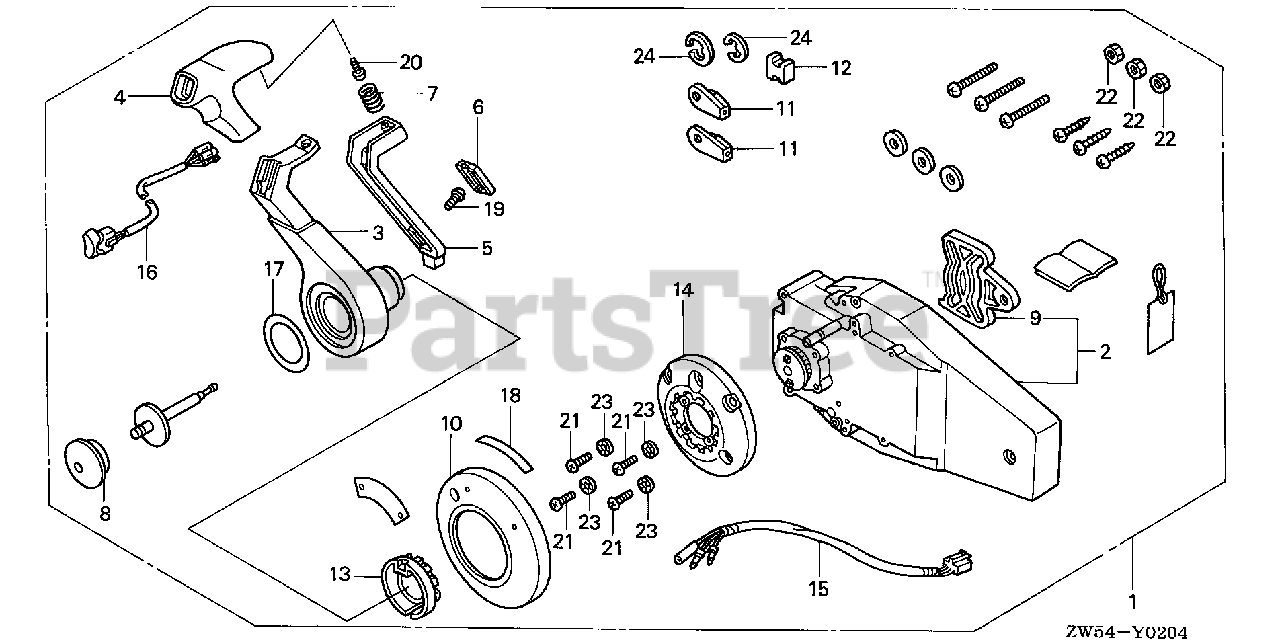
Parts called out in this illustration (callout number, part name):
1	BOX KIT, REMOTE CONTROL
2	HOUSING ASSY., R. (INNER)
3	HANDLE, REMOTE CONTROL
4	COVER, GRIP
5	ARM, NEUTRAL LOCK
6	COVER, LOCK ARM
7	SPRING, NEUTRAL LOCK ARM
8	BUTTON, THROTTLE
9	PLATE, DWELL
10	COVER ASSY.
11	TERMINAL, CABLE
12	SPACER, CABLE CLAMP
13	HOLDER, NEUTRAL LOCK
15	SUB-HARNESS ASSY., POWER
16	SWITCH ASSY., POWER TRIM-TILT
17	MARK, HANDLE FLUSH MOUNT
18	MARK, FLUSH MOUNT
19	SCREW, TRUSS (4X12)
20	SCREW, PAN (5X10)
21	SCREW, PAN (5X30)
22	NUT, HEX. (6MM)
23	WASHER, LOCK (5MM)
24	E-RING (6MM)
